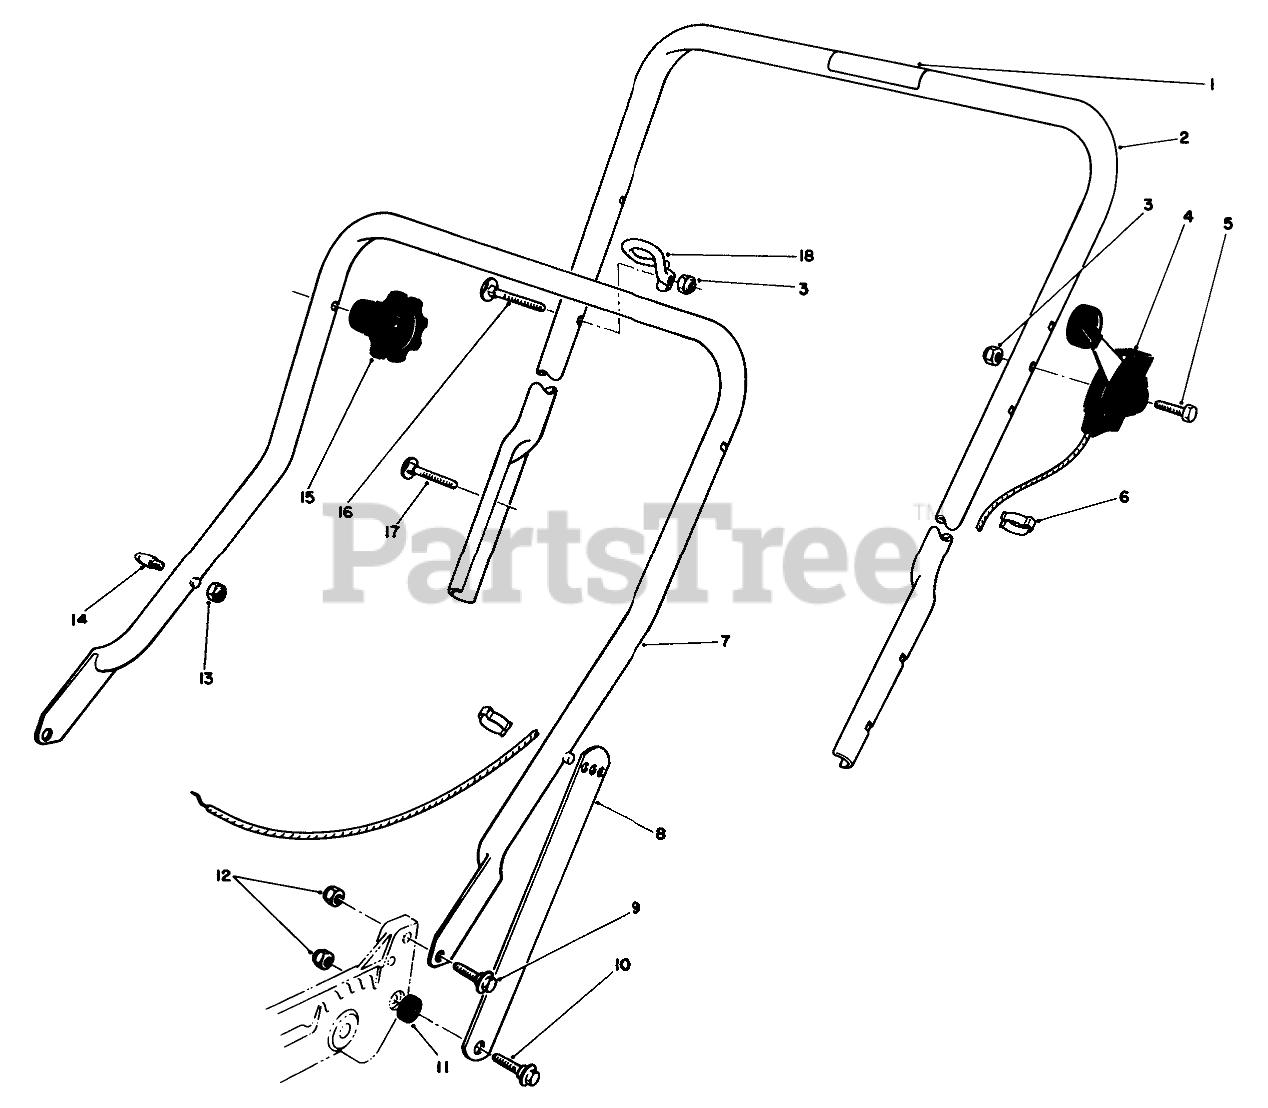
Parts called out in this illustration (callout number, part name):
1	Decal-Danger
2	Handle-Upper (Incl. Ref. #1)
3	Locknut
4	Control-Throttle Bend Type #1 Sheath Lg. 42 inch Wire Lg. 2-3/16 inch
5	SCREW-HH
6	BOWDEN CLIP
7	LOWER HANDLE ASM
8	Handle Latch
9	SCREW-SHOULDER
10	SCREW-SHOULDER
11	SPACER
12	NUT-LOCK, NI
13	NUT-LOCK, NI
14	HANDLE PIN
16	HANDLE SCREW
17	5/16-18 X 2 HNDLE SCREW
18	Guide
